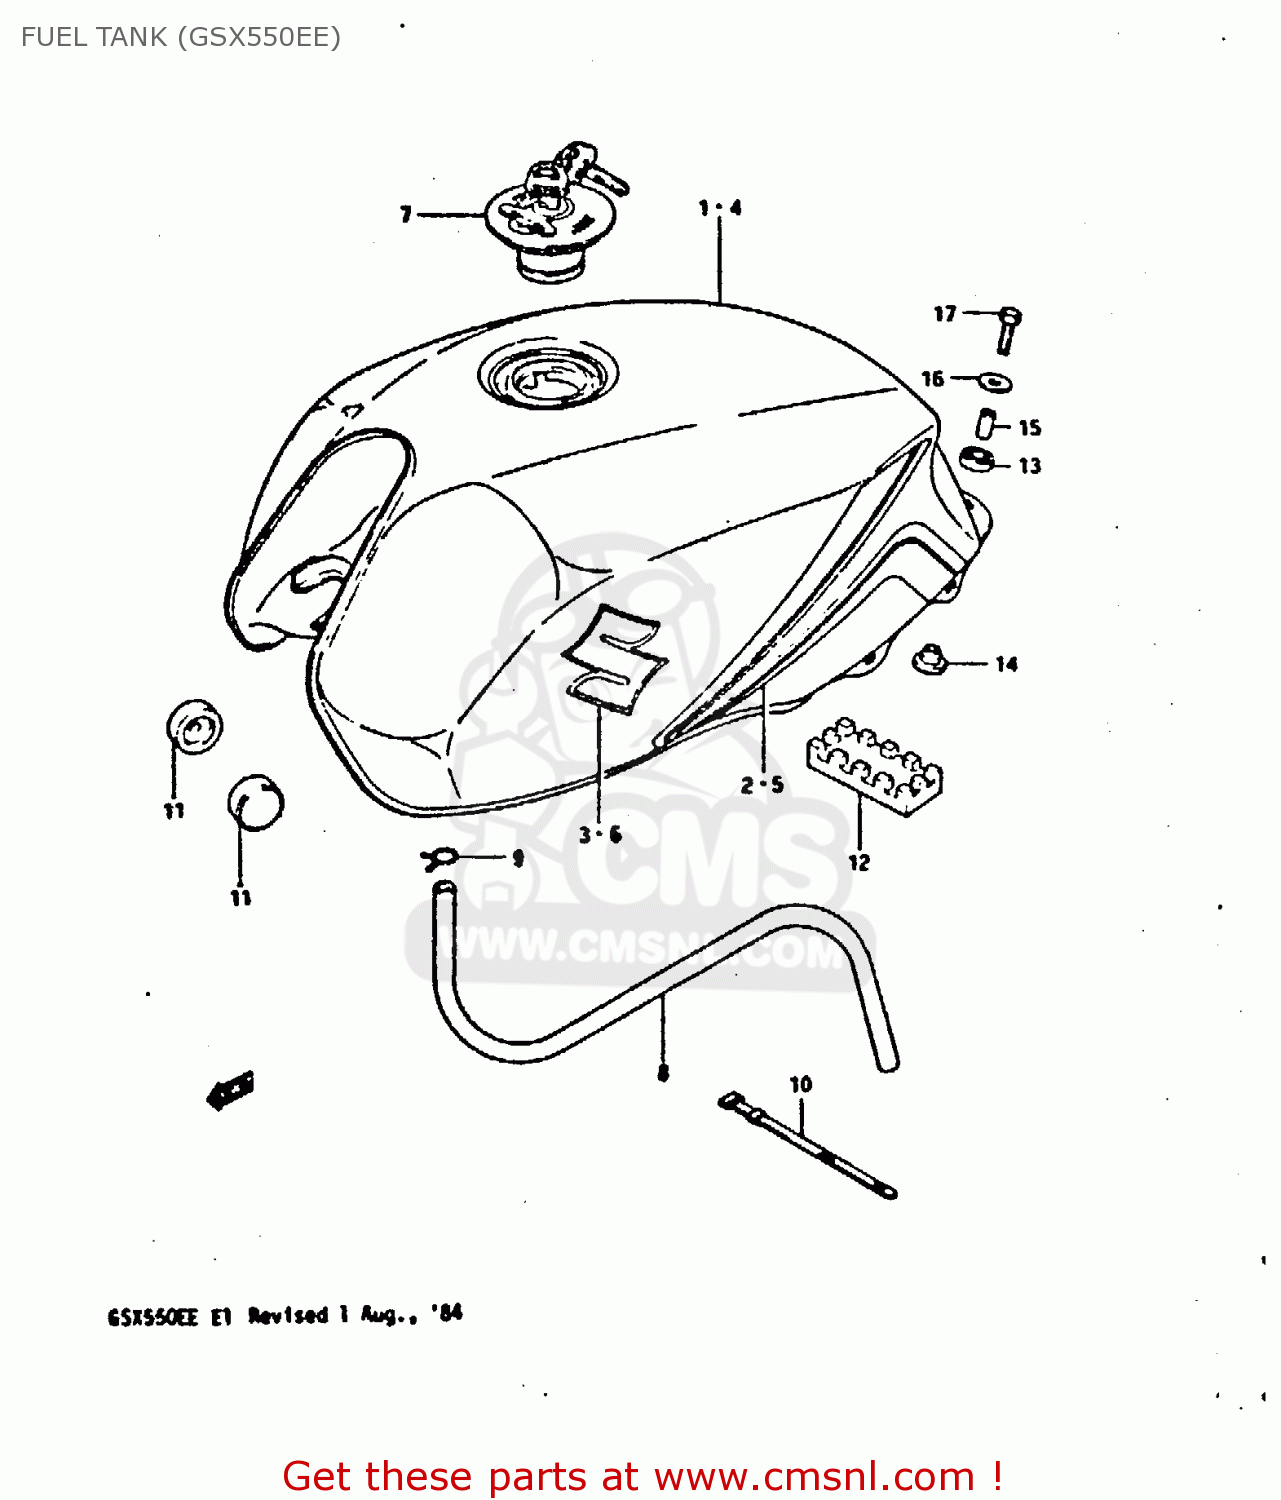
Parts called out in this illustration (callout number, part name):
1	TANK ASSY, FUEL (BLACK)
2	TAPE SET, FUEL TANK
3	EMBLEM
4	TANK ASSY, FUEL (RED)
5	TAPE SET, FUEL TANK
6	EMBLEM
7	CAP ASSY,FUEL TANK
8	HOSE,FUEL
9	CLIP
10	CLAMP(L:187)
11	CUSHION
12	CUSHION,FUEL TANK
13	CUSHION
14	CUSHION
15	SPACER (6.4X9X20)
16	WASHER (6.5X24X1.6)
17	BOLT
